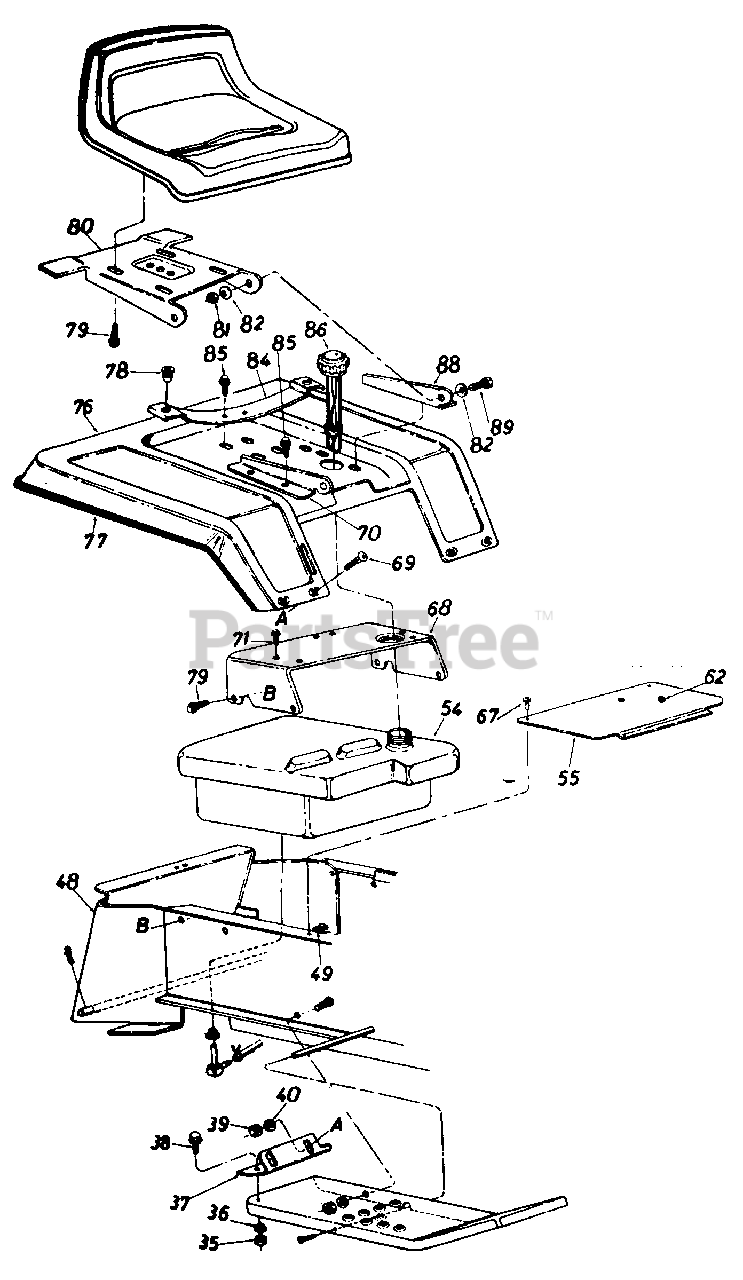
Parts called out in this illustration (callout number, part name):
35	Hex Nut 5/16-18 Thd.*
36	Bell-Wash. .34" I.D.
37	Fender Brkt. R.H.
39	Hex Nut 1/4-20 Thd.*
40	L-Wash. 1/4" I.D.*
48	Hitch Plate
49	Speed Nut
54	Fuel Tank
55	Transmission Cover Ass'y.
62	Snap Bushing
67	Fastener
68	Seat Mounting Channel
69	Carriage Bolt 1/4-20 x .50" Lg.*
70	Seat Bracket R.H.
71	Hex Wash. Hd. Self-Tap Scr. 5/16-24 x .50" Lg.
78	Grommet
79	Hex Wash. Hd. AB-Tap Scr. 3/8 x .75" Lg.
81	Hex Cent. L-Nut 5/16-18 Thd.
82	Belleville Wash. .34" I.D. x .88" O.D.
84	Seat Spring
85	Hex Wash. Hd. Self-Tap Scr. 5/16-24 x .50" Lg.
86	Gas Cap w/ Gauge
88	Seat Bracket L. H .
89	Hex Bolt 5/16-18 x .75" Lg.
